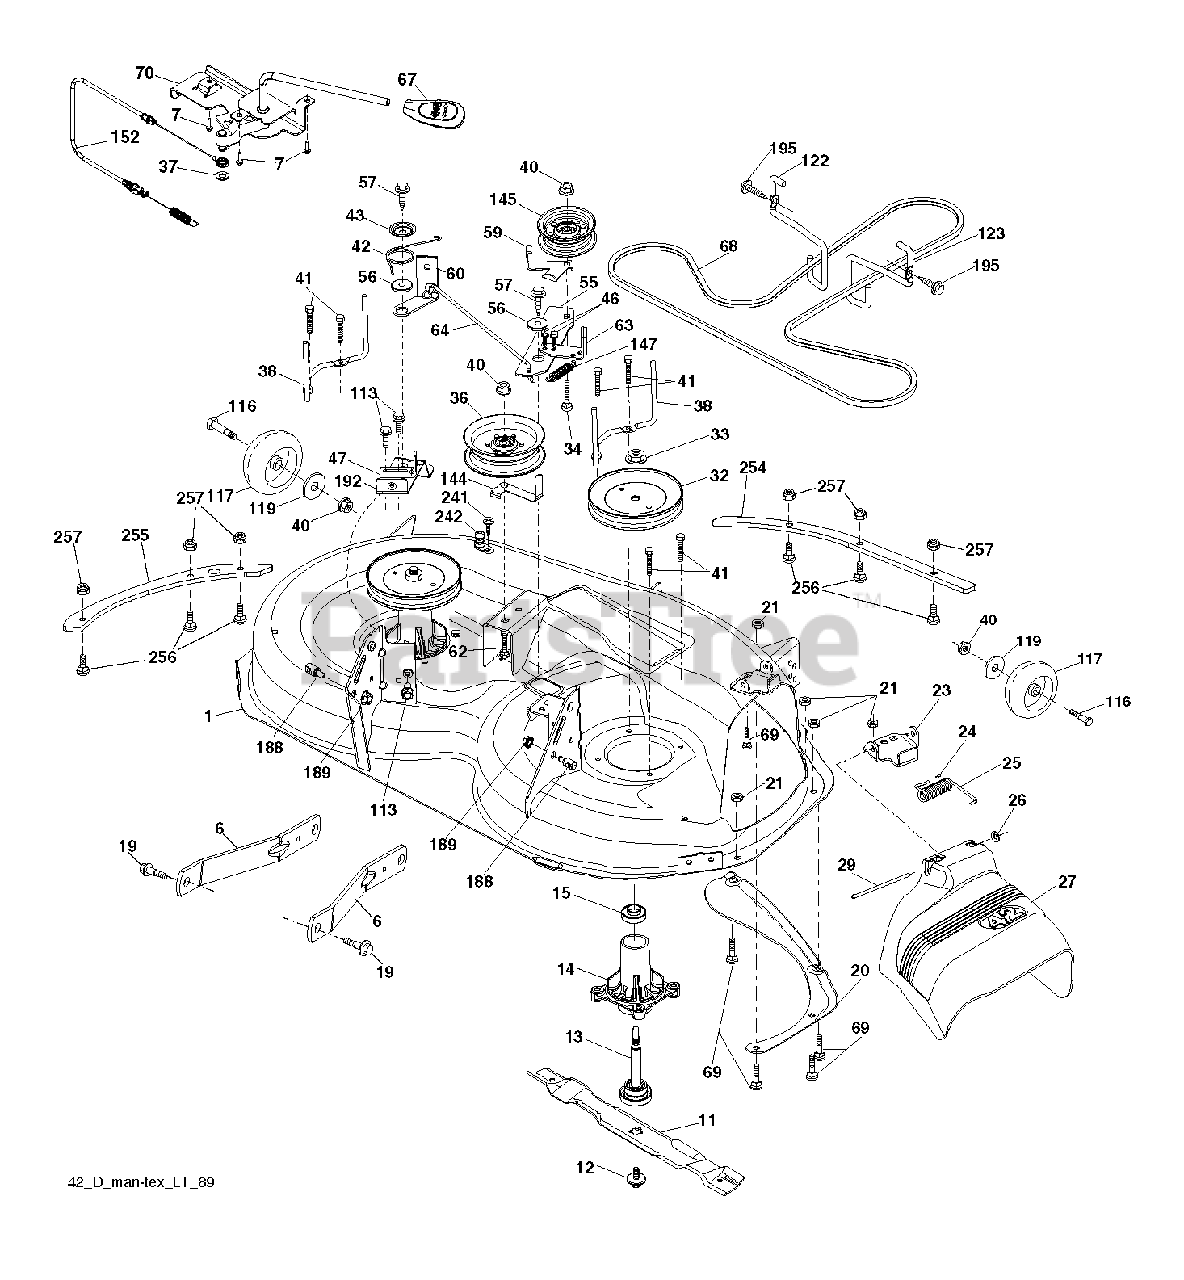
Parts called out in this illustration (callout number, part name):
1	DECK.SVC.42"2GW
6	ARM.SUSPENSION.MOWER.R
7	SCREW.#10 X 0.750.BOS
11	42" HI-LIFT BLADE
12	SCREW.SEMS.7/16-20X1.HEX.HEAD
13	SHAFT ASM.MNDRL.N/GREASEABLE
14	HOUSING.MANDREL.4PT.
15	BEARING.MANDREL.TOP.EXTENDED
19	BOLT.SHOULDER
20	BAFFLE.VORTEX
21	LOCKNUT
23	BRKT.DEFLECTOR.38"2005+
24	CAP-SLEEVE LT
25	SPRING.TORSION.DEFLECT
26	NUT PUSH M
27	SHIELD.DEFLECTOR.MOWER.42"BLAC
29	ROD.HINGE
32	PULLEY.MANDREL.5.438.PD
33	NUT.FLANGE.LOCK.TOP
34	BOLT.3/8-16X1.50
36	PULLEY.IDLER.2006
37	WASHER
38	KEEPER.BELT.MANDREL.PULLEY
40	NUT LOCK FLG 3/8-16 UNC
41	BOLT.HEX.WASHR.HED.313-18X1.19
42	SPRING.TORSION.BRAKE
43	SRPING.TORSION.RETAINE
46	SCREW.1/4-20X5/8
47	BRKT.CLUTCH.CABLE
56	SPACER.RETAINER
57	SCREW 3/8-16X1
59	GUARD, BELT
60	ARM BRAKE MOWER
63	ARM BRAKE MOWER
64	LINKAGE.BRAKE.ASM.ZINC
67	HANDLE.CLUTCH.CABLE.LT
68	BELT.DECK.DRIVE.42"
69	BOLT
70	CLUTCH.ASM.MANUAL.YT.PREDATORQ
113	BOLT.5/16HEX.WHS.HD
116	BOLT M
117	Gage Wheel, Rally Narrow
119	WASHER
122	KEEPER BELT ENGINE LH
123	KEEPER BELT RH
144	KEEPER.BELT.MOWER
145	PULLEY.IDLER.48"PRIMARY
147	RETURN SPRING
152	CABLE.CLUTCH.CABLE.W/SPRING
188	STUD.FASTNER.W/ANTI-ROTATE
189	NUT LOCK HEX FLANGE 5/16-18
192	BRKT.BRAKE.STAND.LH.
195	SCREW, 3/8-16X3/4
241	SCREW.TT.#10-32X.5.3/8.FLANGE
242	PORT.WASHOUT
254	PLATES.RENFRC.42DECK.PT431FRNT
255	PLATES.RENFRCE.42DECK.X431SIDE
256	RHSNB, 1/4-20 X 1, GR5
257	NUT T
